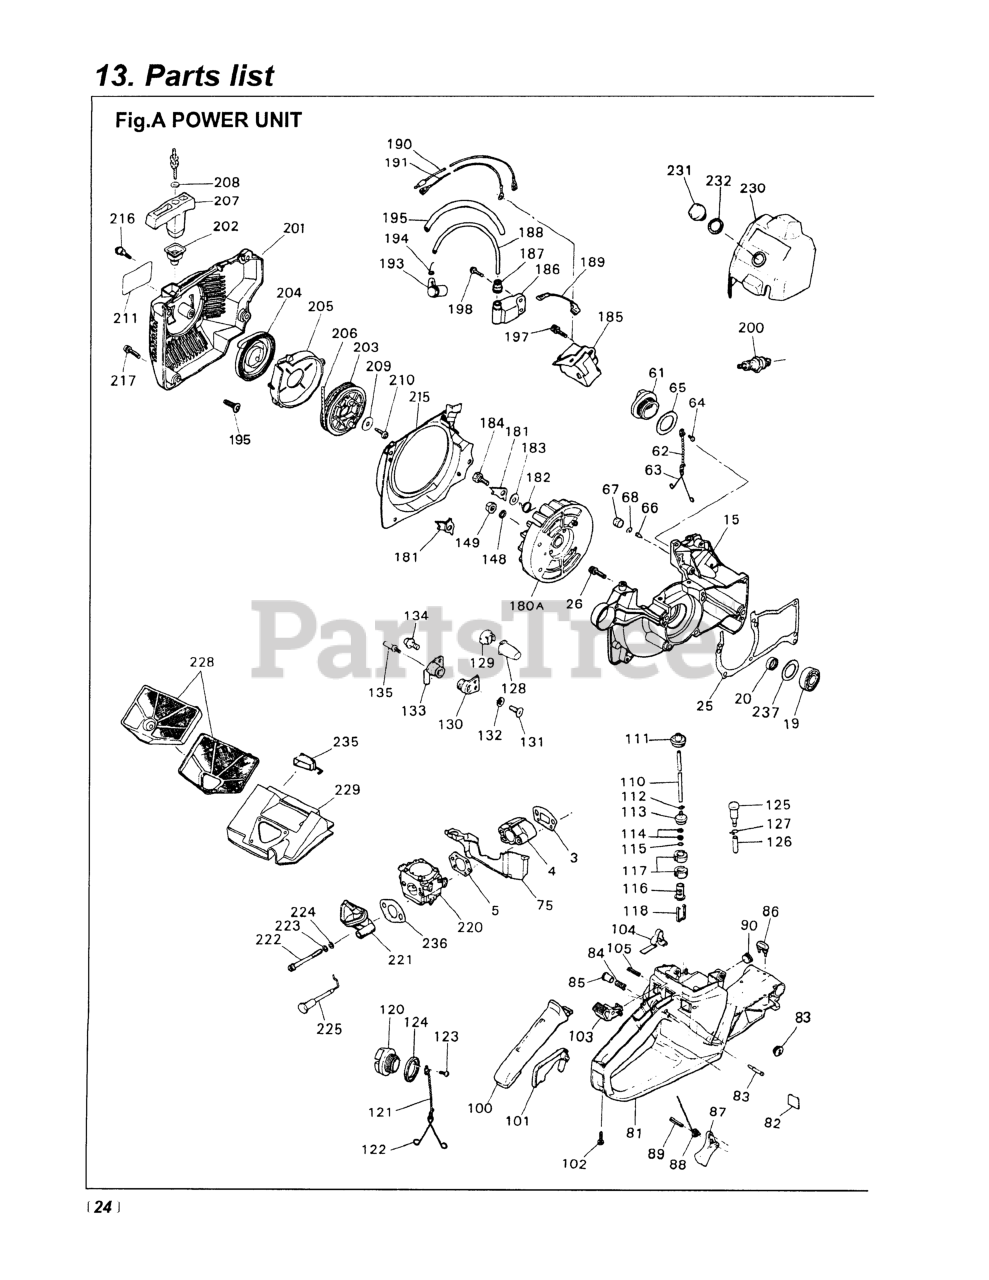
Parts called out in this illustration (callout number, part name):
3	2616-14112 (RPLS-14110)
4	INSULATOR
20	SEAL, OIL
26	BOLT M5 x 20 (RPLS -12280)
64	SCREW, M4 x 10
65	GASKET
66	VALVE (RPLS -23120)
67	SEAL, BREATHER
68	CLIP
75	SEAL, CYLINDER
81	HANDLE (RPLS -33104)
83	STOPPER
85	KNOB
86	DAMPER (REPLACES 3356-33281)
88	SPRING
90	DAMPER (RPLS -33411)
100	GRIP COVER
102	SCREW
103	SWITCH LEVER
104	SPRING
105	PIN, SPRING
110	PIPE, SUCTION
111	GROMMET
112	CLIP (REPLACES 2841-31280)
120	TANK CAP ASSY
123	SCREW, M4 x 10
124	GASKET
125	BREATHER ASSY (RPLS 2630-31270
127	CLIP (REPLACES 2841-31280)
128	DAMPER (RPLS -35111)
129	CAP (RPLS -35120)
130	DAMPER (RPLS -35150)
131	SCREW, M5 X 14
133	DAMPER (REPLACES -35131)
134	SCREW
148	WASHER, M10 X 25
149	NUT
180A	ROTOR (RPLS -71110)
181	RATCHET
182	SPRING (REPLACES -71130)
184	BOLT
186	COIL, IGNITION
187	CAP
189	CORD
190	CORD
193	CAP, PLUG
194	SPRING PLUG (RPLS 3310-71320)
197	BOLT
198	SCREW (REPLACES -30414)
201	STARTER ASSY (RPLS. -75003)
201	CASE (RPLS -75101)
202	GUIDE
203	REEL
204	SPRING COMP (RPLS. -75301)
206	ROPE
207	KNOB, STARTER
210	SCREW
215	COVER
217	SCREW
220	CARBURETOR (HDA-212-1)
221	MANIFOLD (RPLS -82112)
223	WASHER, SPRING M4 x 1.3
224	WASHER, M5 X .8
225	ROD, CHOKE
229	SILENCER
230	COVER (RPLS -83300)
232	GASKET, KNOB
235	CAP, SILENCER
237	RING
NI	OIL PIPE COMP
NI	BAND COMP
NI	COVER COMP. (RPLS-31103)
NI	R HANDLE ASSY (RPLS -33002)
NI	PIPE ASSEMBLY
NI	FILTER ASSY
NI	BREATHER ASSEMBLY
NI	SHIM (REPLACES 848-870-G000)
NI	CLUTCH ASSY (RPLS -51200)
NI	ROTOR COMP.
